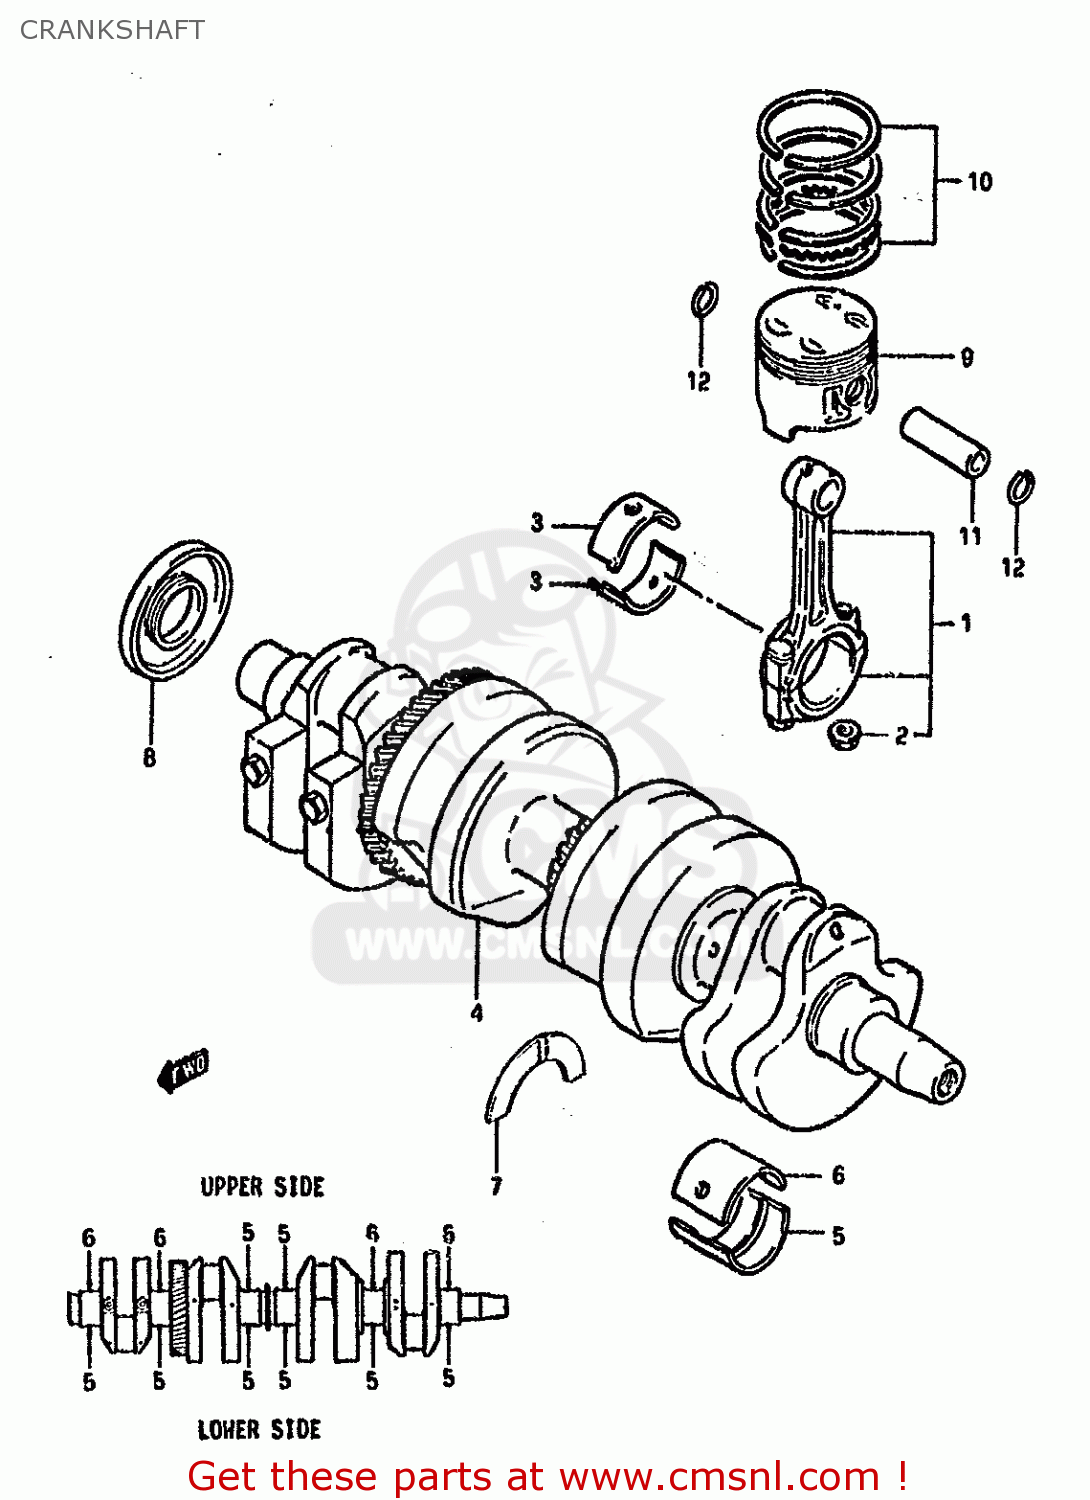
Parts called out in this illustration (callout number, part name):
1	ROD ASSEMBLY,CONNECTING
2	NUT
3	BEARING,CRANK PIN
4	CRANKSHAFT
5	METAL CRANKSHAFT
6	METAL CRANKSHAFT
7	PLATE,CRANK THRUST
8	OIL SEAL
9	PISTON
10	RING SET,PISTON
11	PIN,PISTON (18MM)
12	CIRCLIP,PISTON PIN
